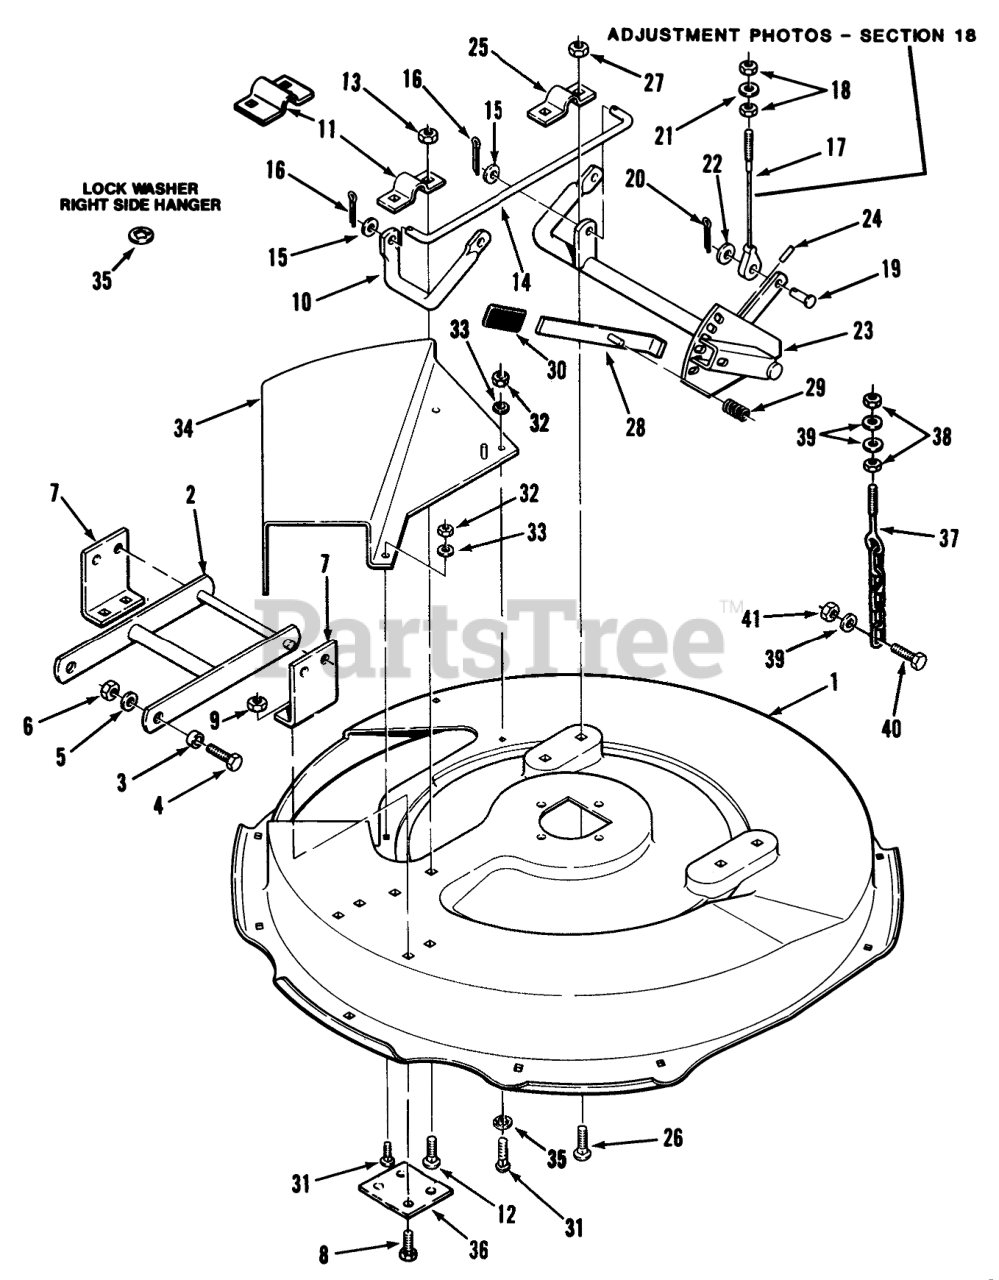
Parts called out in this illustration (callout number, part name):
1	DECK 30" MOWER R
2	ASSY MWR FRONT MO R
3	SPACER
4	BOLT
5	Washer
6	NUT
7	BRKT FRONT MOWER R
8	BOLT
9	NUT
10	ROD HEIGHT ADJ R
12	Bolt
13	NUT
14	ROD HEIGHT ADJUST
15	Washer
16	Cotter Pin
17	CABLE MOWER SUPPORT
18	Nut
19	CLEVIS PIN
20	Cotter Pin
21	WASHER 5/16 SAE
22	Washer
23	HEIGHT ADJ ASSY R
24	SPIROL PIN
26	Bolt
27	NUT
28	LEVER ASSY
29	SPRING-COMPRESSION
31	Bolt 1/4-20 X 5/8
32	Nut
34	Mower Deflector
35	Washer-Lock
36	PLATE-BACKUP R
37	CHAIN-SUPPORT
38	Nut
39	WASHER 5/16 SAE
40	Nut
41	Bolt
